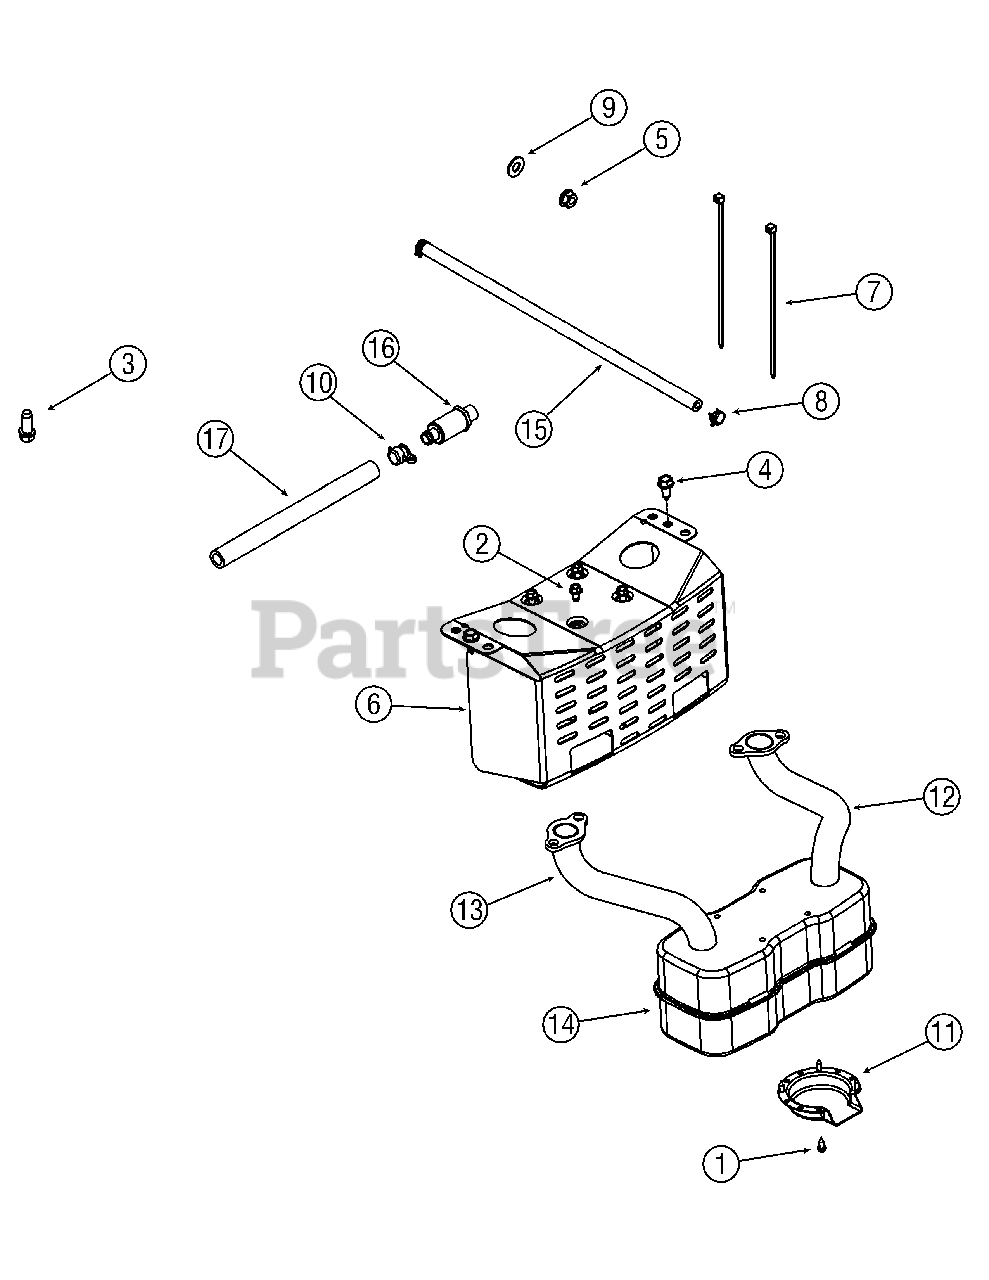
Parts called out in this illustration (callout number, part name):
1	Screw, #8-18, 0.500
2	Screw, Hex, 1/4-20, 0.500
3	Screw, Sems, 3/8-16, .75
4	Screw, Hex, 5/16-12 x .75
5	Hex Flange Nut, 3/8-16
7	Cable, Tie, 3/16 x .05 x 7.4
8	Clamp, Hose
9	Lock Washer,.406 x.875 x.059
10	Cap, Oil Drain
11	Deflector, Muffler
12	Pipe, Exhaust, LH
13	Pipe, Exhaust, RH
14	Muffler, Dual Inlet
15	Fuel Hose, Low Permeation
16	Drain, Oil
17	Extension Hose, Oil Drain
